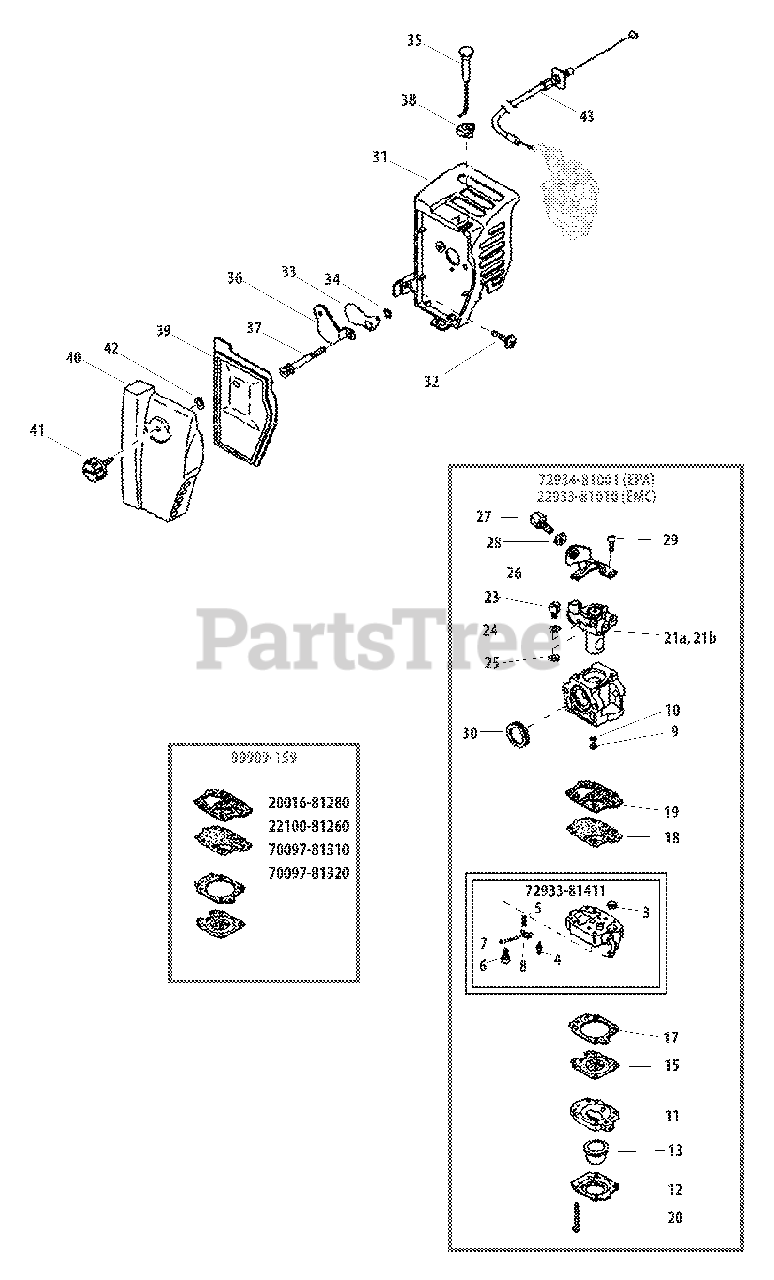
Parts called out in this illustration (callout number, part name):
3	STRAINER
4	VALVE, INLET NEEDLE
5	SPRING, METERING LEVER
6	SCREW, METERING LEVER PIN
7	PIN, METERING LEVER
8	LEVER, METERING
9	JET, MAIN - 37
10	O-RING
11	BASE, PURGE
12	RETAINER, PURGE BULB
13	BULB, PURGE
15	DIAPHRAGM, METERING
17	GASKET, METERING
18	DIAPHRAGM, PUMP
19	GASKET, PUMP
20	SCREW, PUMP COVER
21A	THROTTLE VALVE SET
21B	THROTTLE VALVE ASSY
23	SWIVEL
24	WASHER
25	RING, RETAINING
26	BRACKET, CABLE
27	NUT, CABLE ADJUST
28	NUT
29	SCREW
30	SEAL
31	CASE, AIR FILTER
32	SCREW
33	PLATE, CHOKE
34	WASHER
35	ROD, CHOKE
36	PLATE, PREVENT
37	SCREW - 5X45
38	GROMMET
39	FILTER, AIR
40	COVER, AIR FILTER
41	SCREW
42	RING, RETAINING
43	CABLE, THROTTLE
22933-81010	CARBURETOR
72933-81411	BASE, PURGE
72934-81001	CARBURETOR
99909-159	DIAPHRAGM/GASKET KIT
